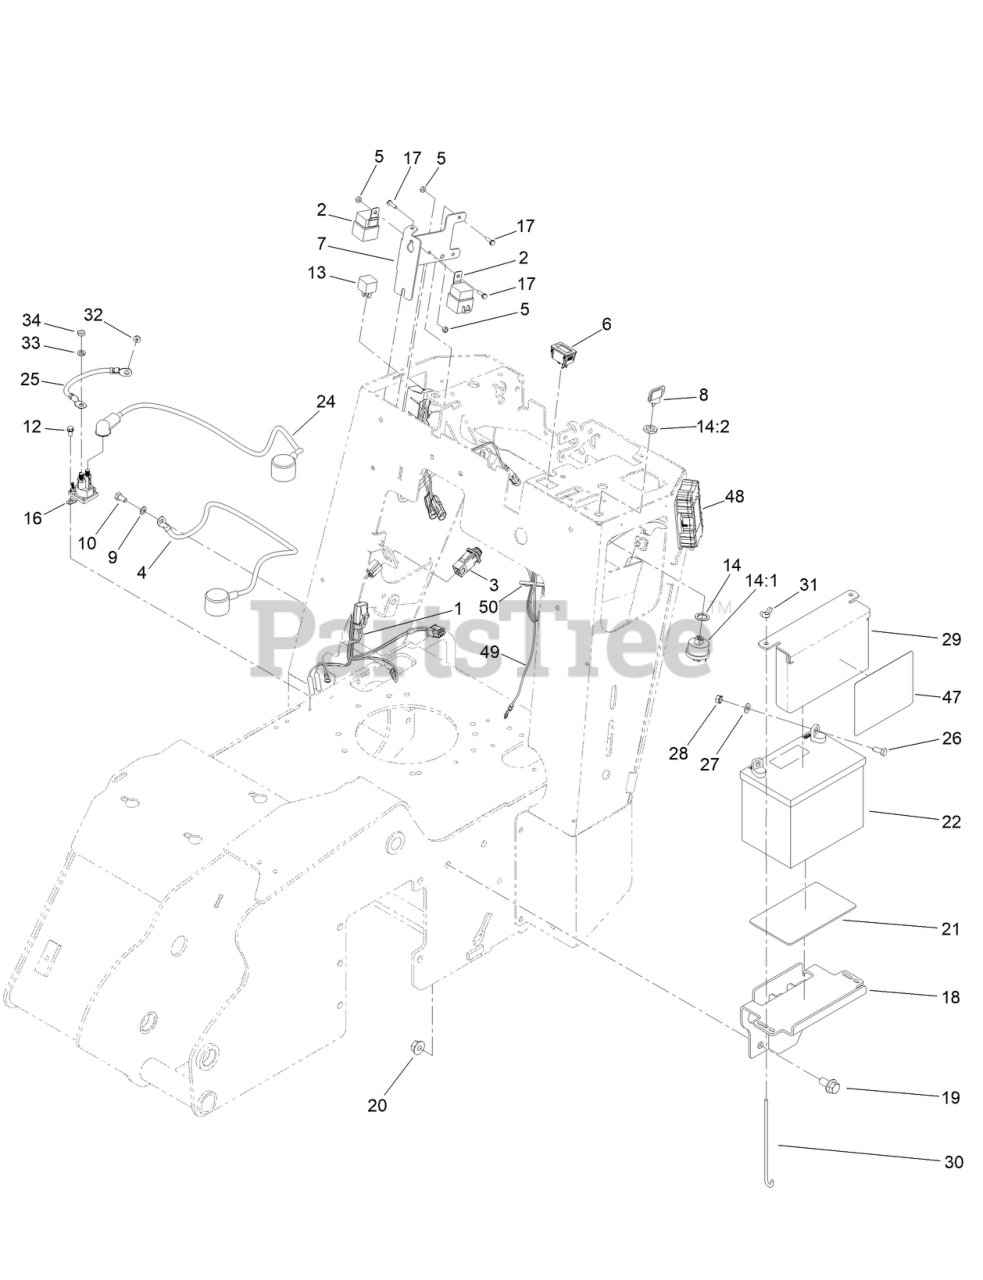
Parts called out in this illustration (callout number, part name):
1	HARNESS-WIRE
2	RELAY-MINI
3	SWITCH-PLUNGER
4	CABLE-BATTERY, NEGATIVE
5	NUT-LOCK, NI
6	HOURMETER
7	BRACKET-ELECTRICAL
8	KEY-IGNITION
9	WASHER-LOCK
10	SCREW-HH
12	SCREW-HWH
13	RELAY
14:1	WASHER-LOCK
14:2	NUT-HH
16	SOLENOID
17	SCREW-HWH
18	TRAY-BATTERY [BLK-TXT]
19	SCREW-HHF
20	NUT-HHF
21	PAD-SKID, ANTI
22	BATTERY-DRY
24	CABLE-BATTERY, POSITIVE ASM
25	CABLE-BATTERY, POSITIVE
26	SCREW-HH
27	WASHER-FLAT
28	NUT-KEPS
29	PLATE-HOLD DOWN,BATTERY
30	BOLT-HOLDDOWN
31	NUT-WING
32	NUT-HF
33	WASHER-LOCK
34	NUT-JAM
47	DECAL-SERVICE
48	M7L-LITE ZTR KIT ASM
49	HARNESS-WIRE, MACHINE ZTR
50	TIE-CABLE
